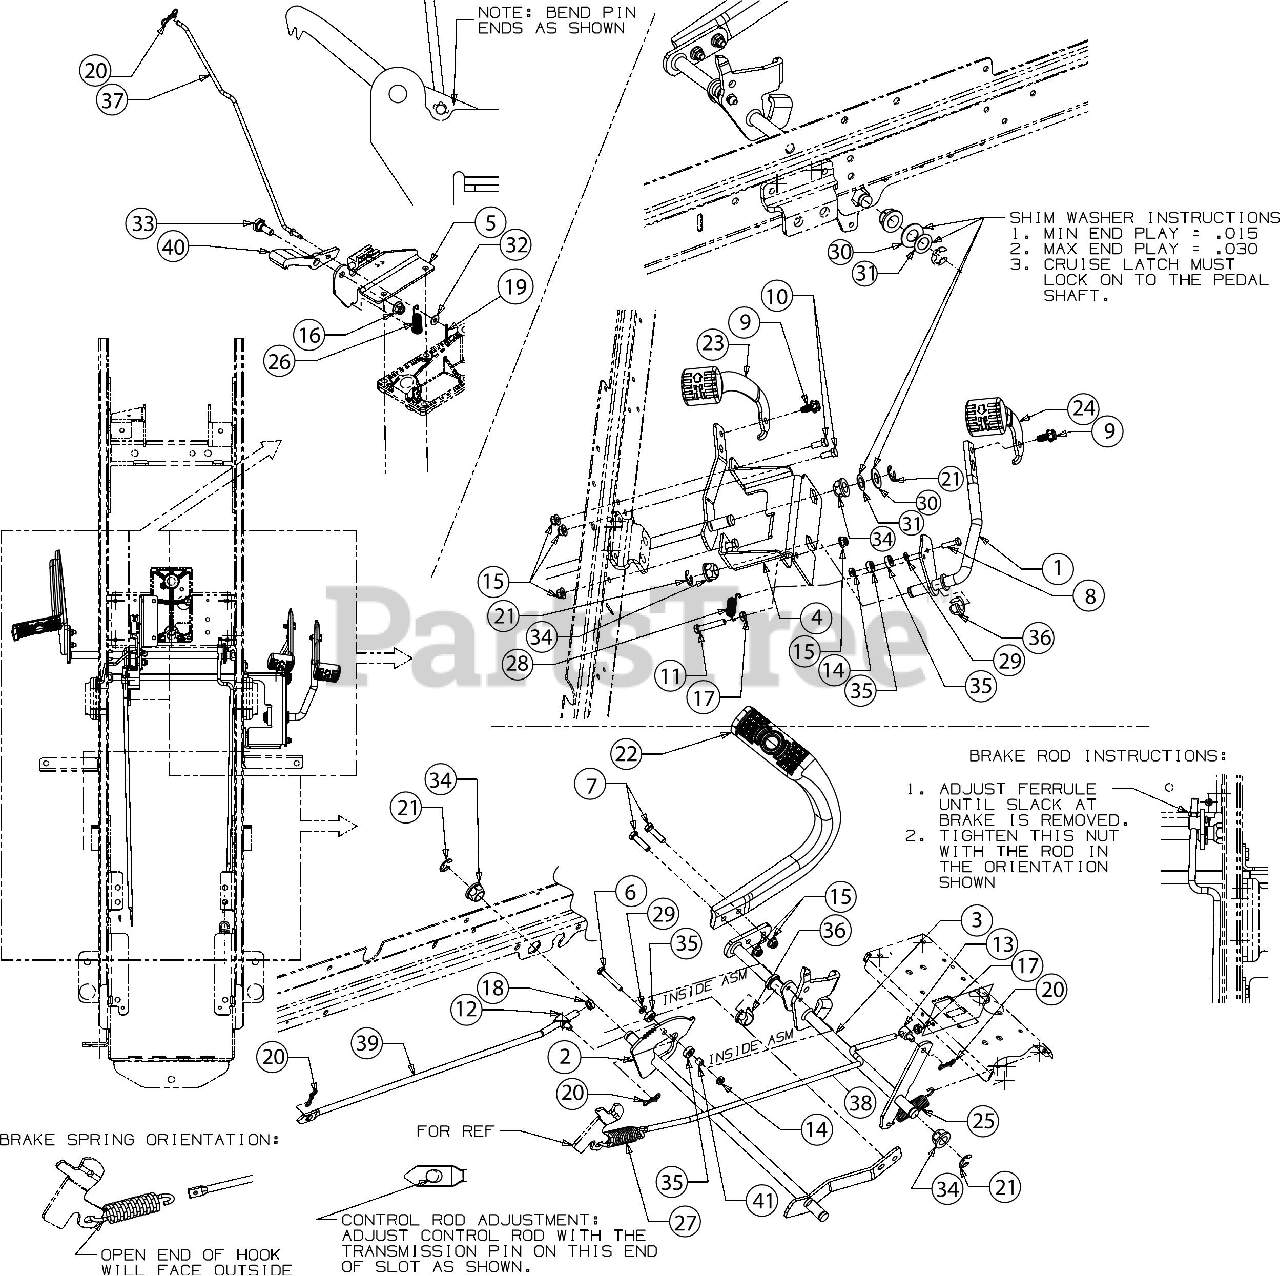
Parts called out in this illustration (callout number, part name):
1	REVERSE PEDAL SHAFT
2	FORWARD PEDAL SHAFT
3	BRAKE SHAFT PEDAL
4	FWD/REV PEDAL BRACKET
5	CRUISE LATCH BRACKET
6	HEX SCREW 1/4-20 x 1.75
7	SCREW 5/16-18 x 1.25 GR5
8	SCREW 1/4-20 X1.00 GR5
9	SCREW 3/8-16 x 3/4
10	SCREW 5/16-18 x .75 GR5
11	SCREW 5/16-18 x 1.75 GR5
12	FERRULE 3/8-16 x .312
13	FERRULE-5/16-18
14	HEX NUT
15	FLANGE LOCK NUT 5/16-18
19	COTTER PIN-3/32
20	BOW TIE COTTER PIN 1/4-5/16
22	BRAKE PEDAL
23	FORWARD PEDAL
24	REVERSE PEDAL
25	EXTENSION SPRING
26	EXTENSION SPRING
27	EXTENSION SPRING .95 OD x 4.0 LG
28	EXTENSION SPRING
29	FLAT WASHER .281 x .50 x .063
30	FLAT WASHER .640ID X1.24OD x .06
31	FLAT WASHER
32	FLAT WASHER .271:.630:.065
33	SHOULDER SCREW
34	FLANGE BEARING
35	BALL BEARING .25 x .6875 x .25
36	SPLIT HEX FLANGE BEARING .628
37	CRUISE CONTROL ROD
38	BRAKE CONTROL ROD
39	HYDRO CONTROL ROD
40	CRUISE LATCH
41	SPACER .375X.25X.335 LG
